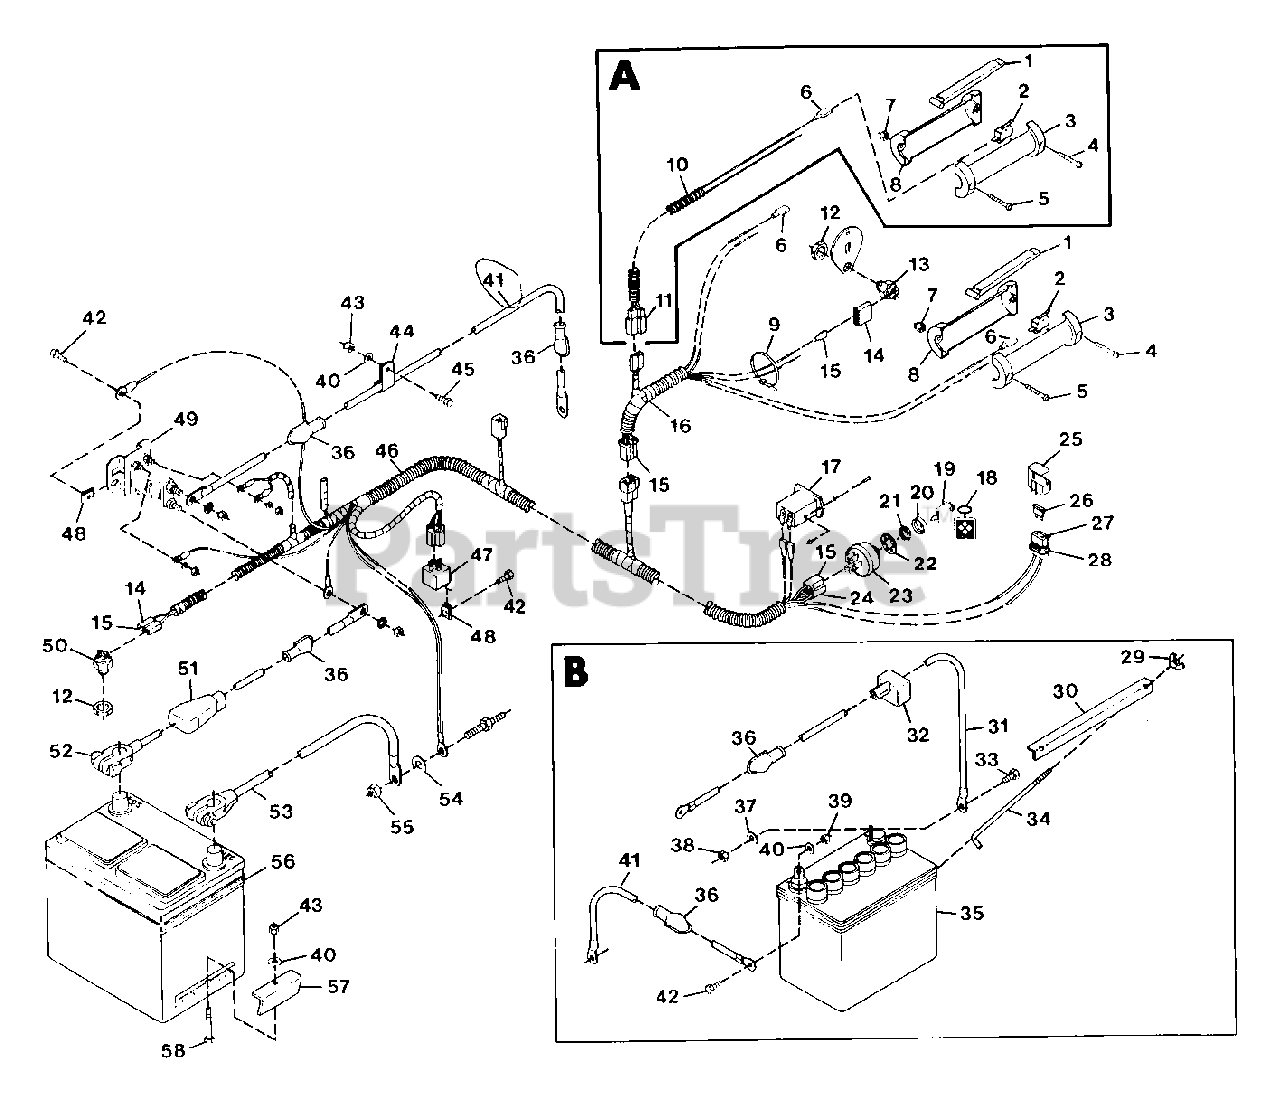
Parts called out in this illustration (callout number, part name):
1	Lever
2	Switch
3	Handle, L.H.
4	Screw, Mach. 10-24x.75 PHD
5	Screw, Mach. 10-24x1.50 PHDCR
6	Terminal, Female
7	Nut, Lock 10-24
8	Handle, R.H.
9	Tie Wrap, Black
10	Harness, Steering Brake
11	Connector
12	Nut, Stamped 9/16-18
13	Switch, Neutral Start
14	Connector, 2-Wire Switch
15	Terminal
16	Harness, Wiring Handlebar
17	Hourmeter
18	Chain, Key
19	Key, Ignition Switch
20	Boot, for 9/16 Switch
21	Nut, 9/16-24 for Switch
22	Washer, Lock
23	Switch, Ignition
24	Connector
25	Cover
26	Fuse, 25 amp
27	Terminal, for 10-12 ga. wire
28	Connector
29	Nut, Wing 1/4-20
30	Hold Down, Battery
31	Cable, Battery to Solenoid (8 HP)
32	Boot, Battery Cable
33	Bolt, Hex 5/16-18x.625
34	Hook, Battery Hold Down
35	Battery, 12 Volt (8 HP)
36	Boot, Battery Cable (10, 12 and 16 HP)
37	Washer, Flat .344x.688x.065
38	Nut, Hex 5/16-18
39	Nut, Hex 1/4-20
40	Washer, Flat .281x.625x.065
41	Cable, Switch to Starter (10,12 and 16 HP)
41	Cable, Negative Battery (8 HP)
42	Bolt, Hex 1/4-20x.625 (10,12 and 16 HP)
43	Nut, Lock 1/4-20
44	Clamp, Nylon
45	Bolt, Hex 1/4-20x.75
46	Harness, Wiring (10,12 and 16HP)
46	Harness, Wiring (8 HP)
47	Relay
48	Nut, Speed 1/4-20
49	Switch, Magnetic
50	Switch, Interlock
51	Cover, Battery Terminal
52	Cable, Positive Battery
53	Cable, Negative Battery (10, 12 and 16 HP)
54	Washer, Flat .469x.938x.065
55	Nut, Lock 3/8-16
56	Battery, 12 Bolt (10, 12 and 16 HP)
57	Clamp (8 HP)
58	Bolt, Hex 1/4-20x2.00
59	Black Tie Wrap
NS	Decal, E.S. Warning
